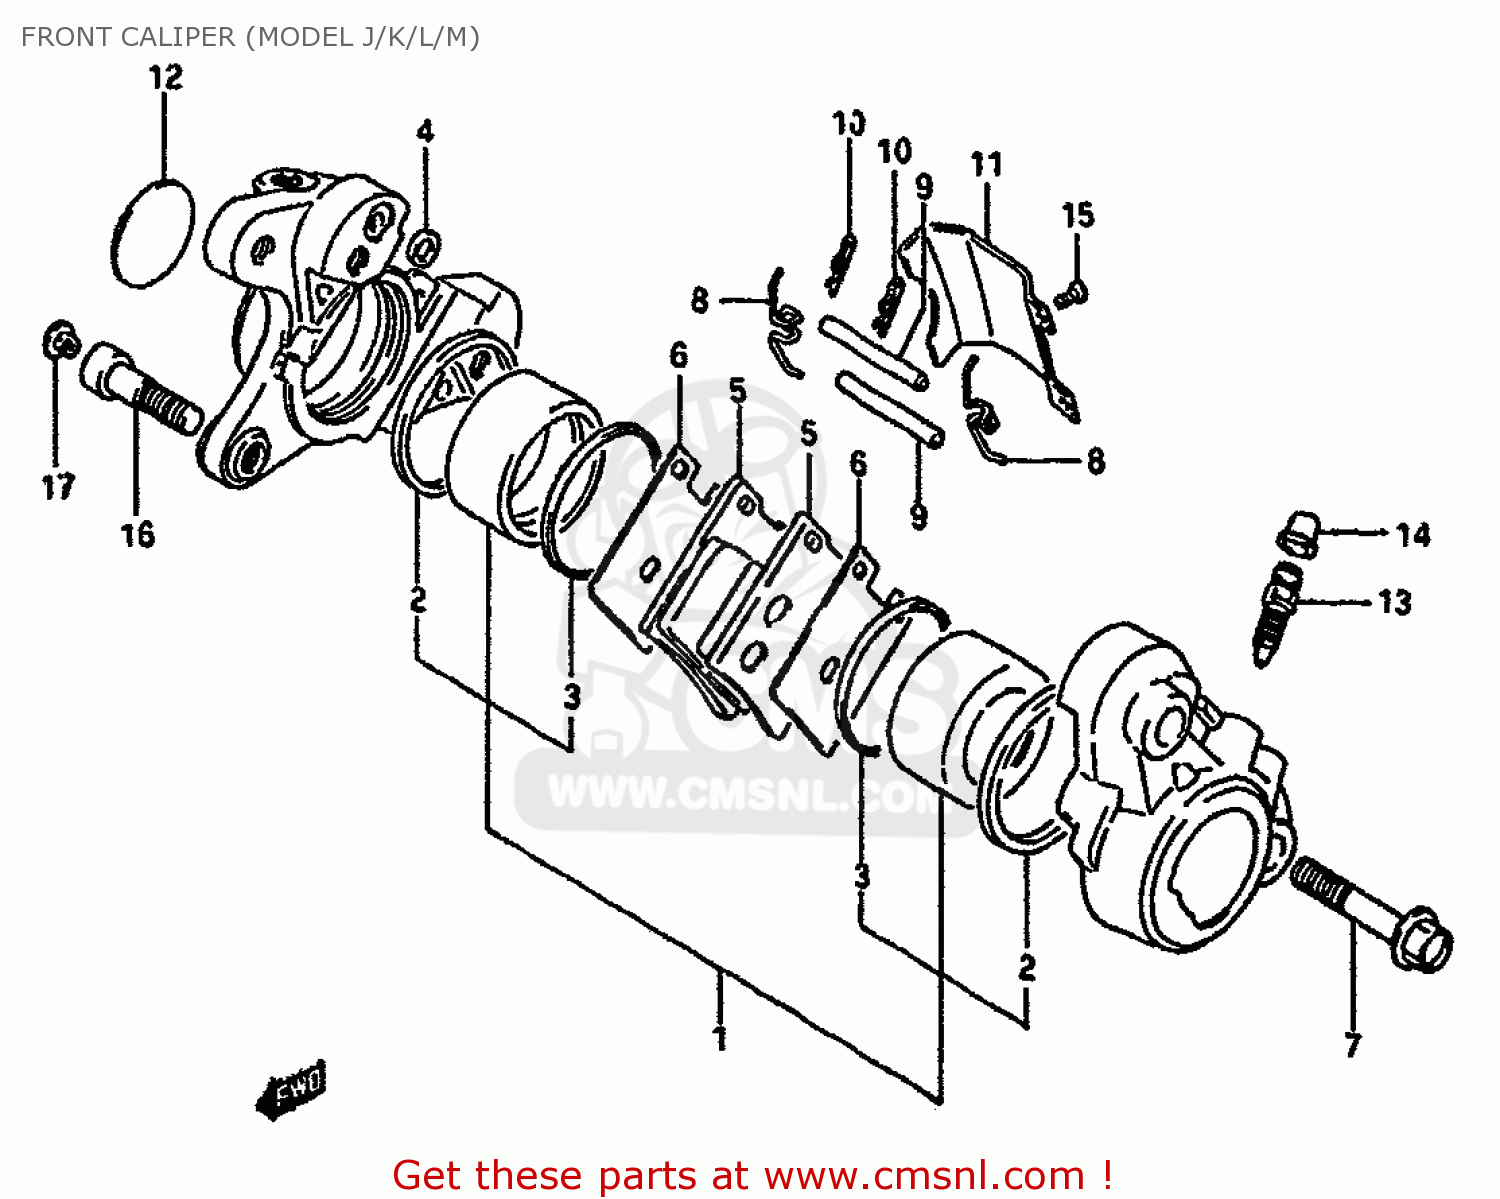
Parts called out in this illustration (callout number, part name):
1	PISTON SET
2	SEAL,FR CALIPE
3	BOOT,PISTON
4	SEAL,JOINT
5	PAD
6	SHIM,PAD
7	BOLT,HOUSING
8	SPRING
9	PIN,PAD
10	CLIP,PAD PIN
11	COVER,CALIPER
12	CAP,CALIPER
13	BLEEDER
14	CAP,BREATHER
15	SCREW,CALIPER COVER (4X
16	BOLT(10X33)
17	CAP(OD:12)
